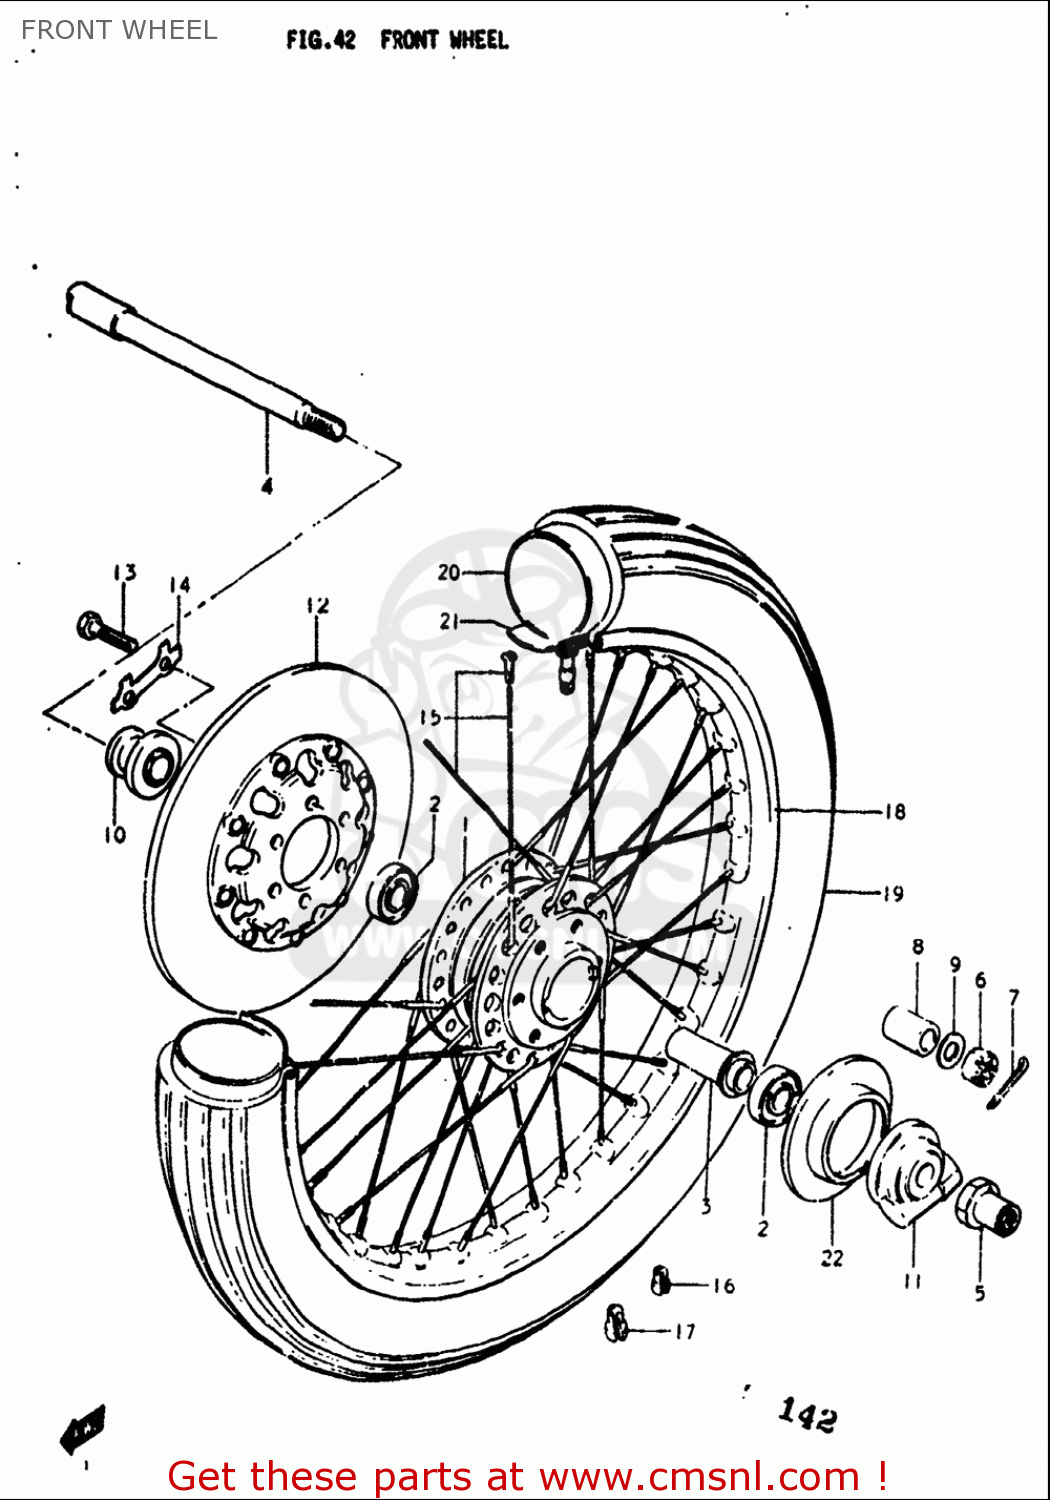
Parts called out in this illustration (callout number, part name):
1	HUB,FRONT WHEEL
3	SPACER,FR HUB BEARING
4	AXLE,FRONT
6	NUT 12MM
7	PIN
8	SPACER(15X22X30)
9	WASHER
10	SPACER,FR AXLE,R
11	BOX ASSY,SPEEDOMETER GEAR
12	DISC,BRAKE
13	BOLT(8X30)
14	WASHER
15	SPOKE ASSY,FR WHEEL
16	BALANCER,WHEEL (30G)
17	BALANCER,WHEEL (B)
18	RIM,FR WHEEL
19	TIRE,FRONT 3.00 S18
20	TUBE ASSY,WHEEL INNER
21	PROTECTOR,INNER TUBE
